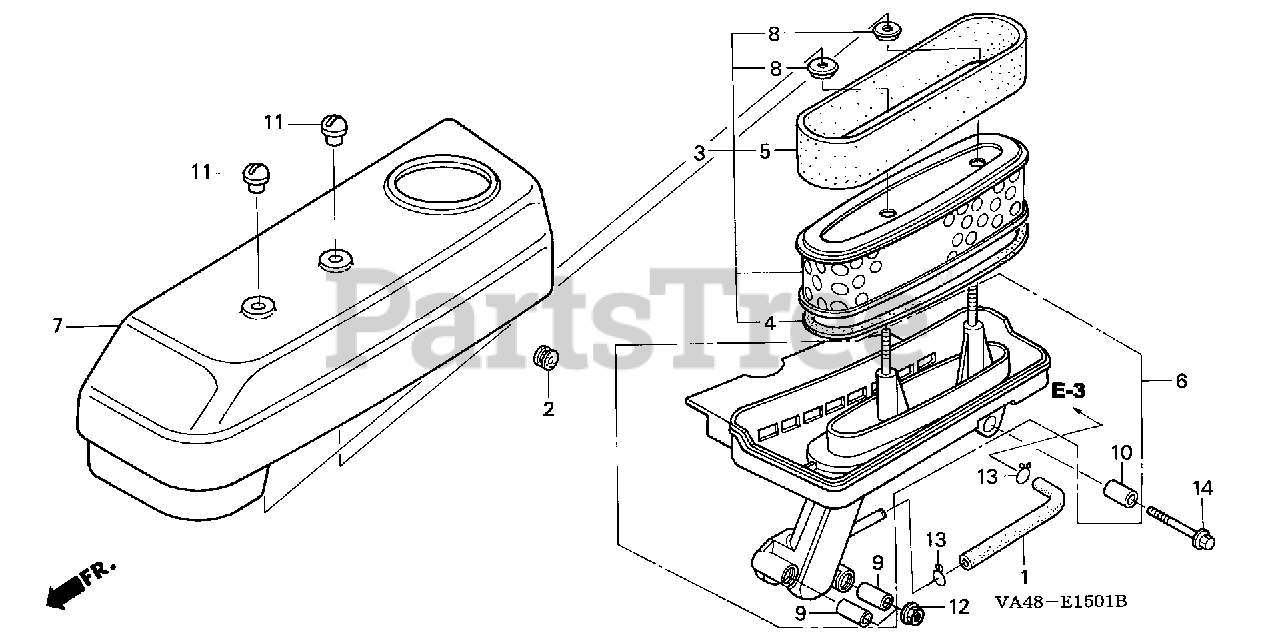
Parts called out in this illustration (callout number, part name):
1	TUBE, BREATHER
2	GROMMET, CHOKE ROD
3	ELEMENT, AIR CLEANER
4	GASKET, ELEMENT
5	FILTER (OUTER)
6	HOUSING, AIR CLEANER
7	COVER, AIR CLEANER *R8* (BRIGHT RED)
8	GROMMET, AIR CLEANER
9	COLLAR, AIR CLEANER
10	COLLAR B, AIR CLEANER
11	NUT, AIR CLEANER COVER (6MM)
12	NUT, FLANGE (6MM)
13	CLIP, TUBE (B12) Use from Engine SN 2086984.
14	BOLT, FLANGE (6X35)
